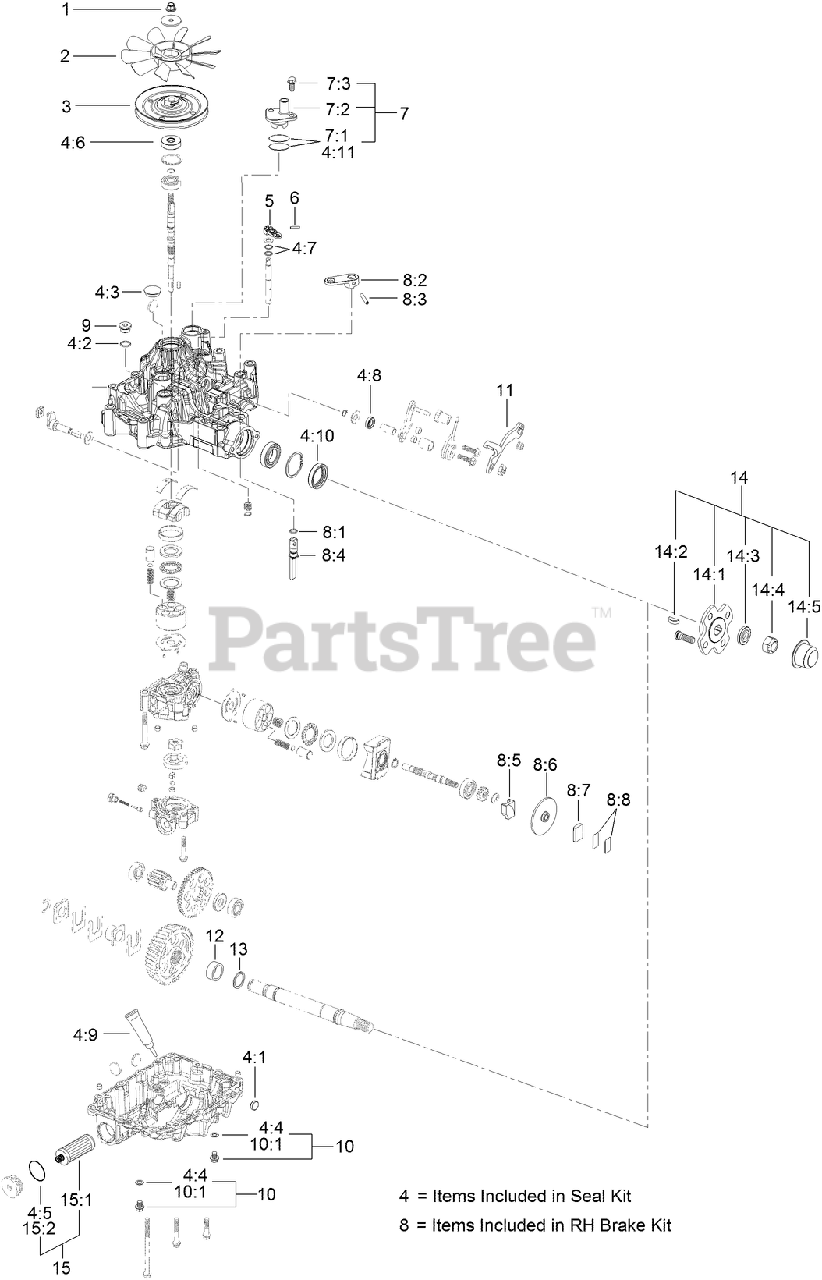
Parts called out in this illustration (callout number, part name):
1	NUT-LOCK
3	PULLEY
4:1	CAP-SEALING
4:2	O-RING
4:3	CAP-SEAL
4:4	Seal-Washer
4:5	Packing
4:6	SEAL-SHAFT
4:7	Deck ASM
4:8	Deck ASM
4:9	SEALANT
4:10	SEAL-AXLE
4:11	Packing
6	LEVER-BYPASS
7	EXPANSION FITTING KIT
7:1	SEAL-FITTING, EXPANSION
7:2	Fitting
7:3	BOLT-FLANGE
8	RH BRAKE KIT
8:1	Deck ASM
8:2	ARM-BRAKE
8:3	Deck ASM
8:4	SHAFT-BRAKE
8:5	ACTUATOR-BRAKE
8:6	DISC-BRAKE
8:7	SHOE-BRAKE
8:8	SHIM KIT
9	CAP-OIL
10	DRAIN BOLT KIT
10:1	Seal-Washer
11	LEVER-CONTROL, RH
12	SLEEVE
13	WASHER
14	AXLE FLANGE KIT
14:1	Deck ASM
14:2	Key-Woodruff
14:3	Deck ASM
14:4	Deck ASM
14:5	NUT-CAP
15	HYDRO FILTER KIT
15:1	FILTER
15:2	O-RING
